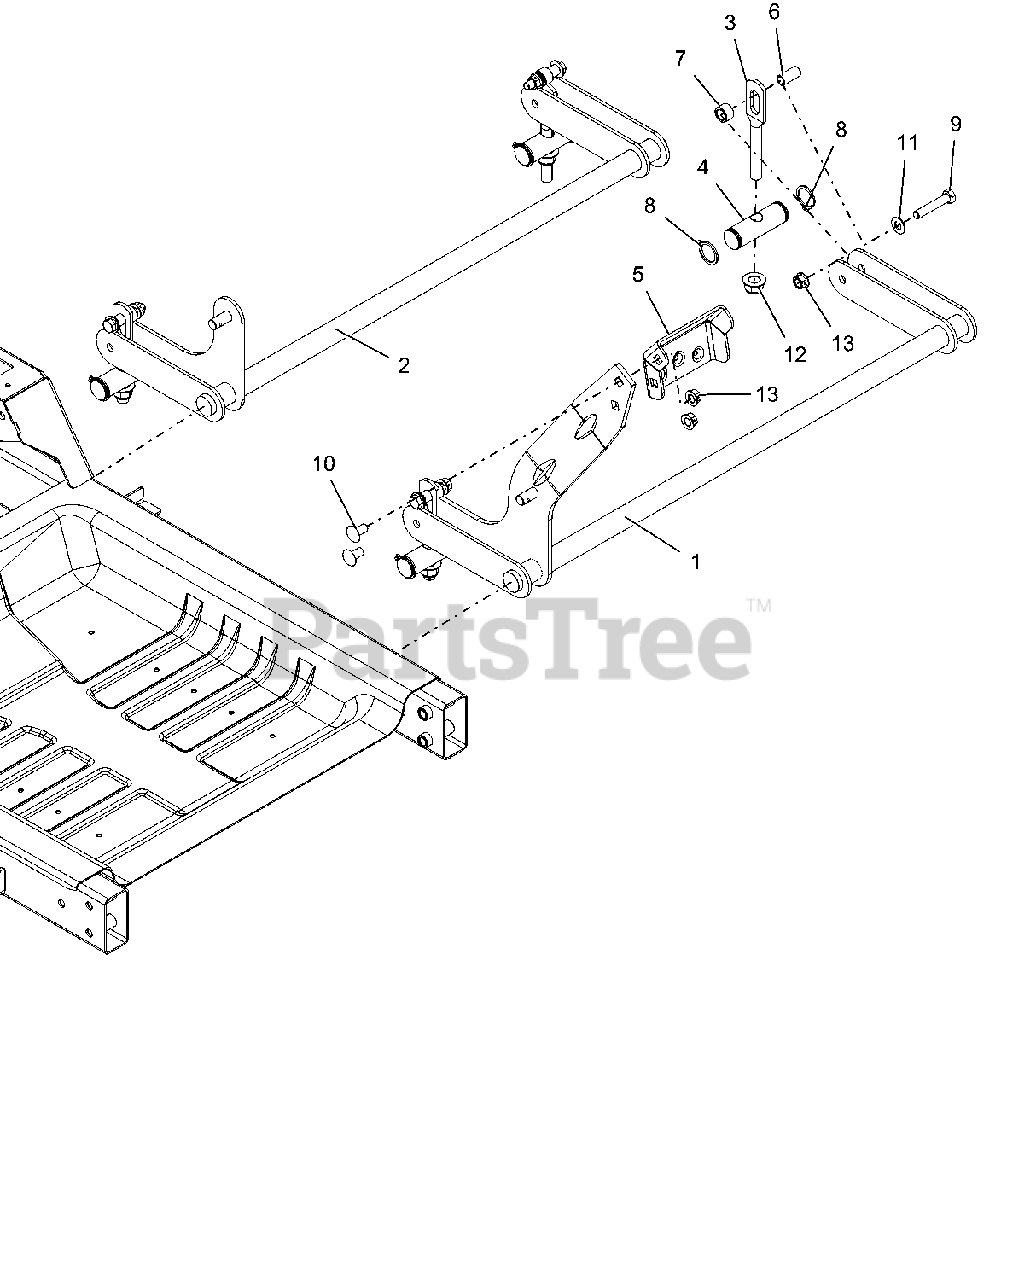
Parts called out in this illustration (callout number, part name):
1	WLDMT, FRONT DECK PIVOT
2	WLDMT, REAR DECK PIVOT
3	LINK, DECK
4	SHAFT, DECK LINK PIVOT
5	PEDAL, DECK LIFT (BOLT ON)
6	BSHG-SLV .385X.500X1.045
7	BSHG-SLV .510X.751X.475
8	RG-RTNG-EXT 1.00X.078
9	BLT-HEX .38-16X2.00 GR8 YWZC
10	BLT,RHSN .38-16X.75 G5 BFP
11	@WSHR-FL-STL.406X.812X.065 YWZ
12	@NUT-LK-NYL-FLG .50-13 YWZC
13	NUT-LK-CTR-FLG .38-16 YWZC
